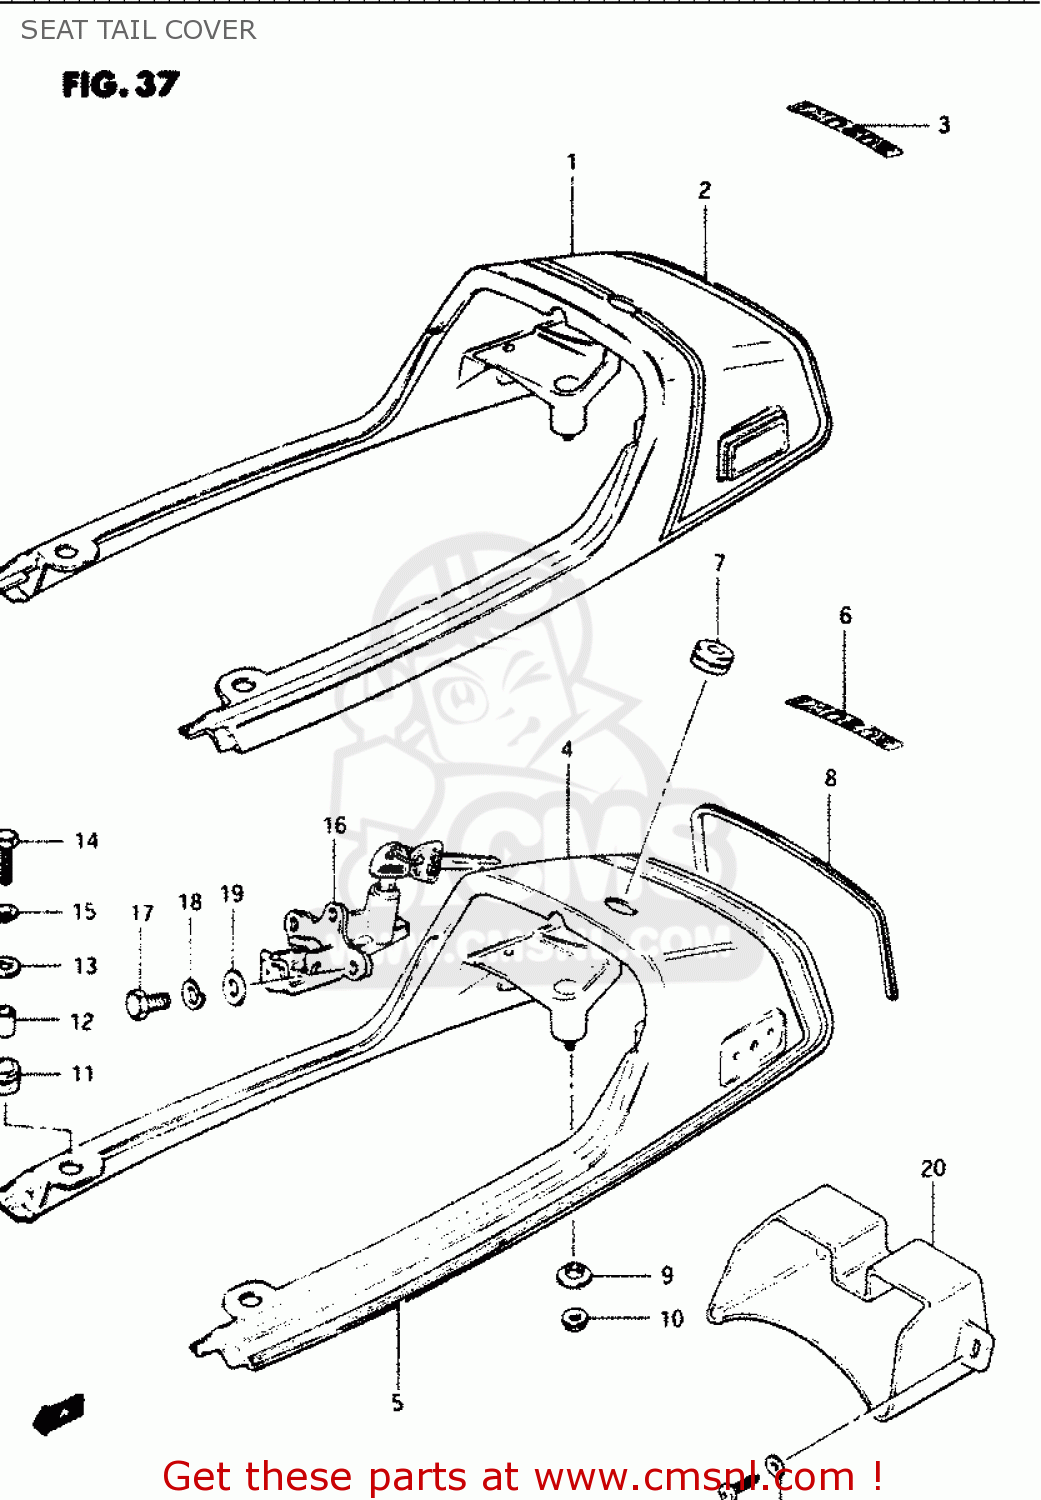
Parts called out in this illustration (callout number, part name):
1	COVER, SEAT TAIL
2	TAPE SET, SEAT TAIL COVER
3	EMBLEM
4	COVER, SEAT TAIL
5	TAPE SET, SEAT TAIL COVER
6	EMBLEM
7	GROMMET,SEAT LOCK HOLE
8	MOLDING,SEAT TAIL COVER
9	WASHER
10	NUT 6MM
11	CUSHION
12	SPACER (7X10X12)
13	WASHER (6.5X24X1.6)
14	BOLT
15	WASHER,LOCK
16	LOCK SET,SEAT
17	BOLT
18	WASHER,LOCK
19	WASHER
20	BOX, SEAT TAIL
21	SCREW 6X12
22	WASHER
